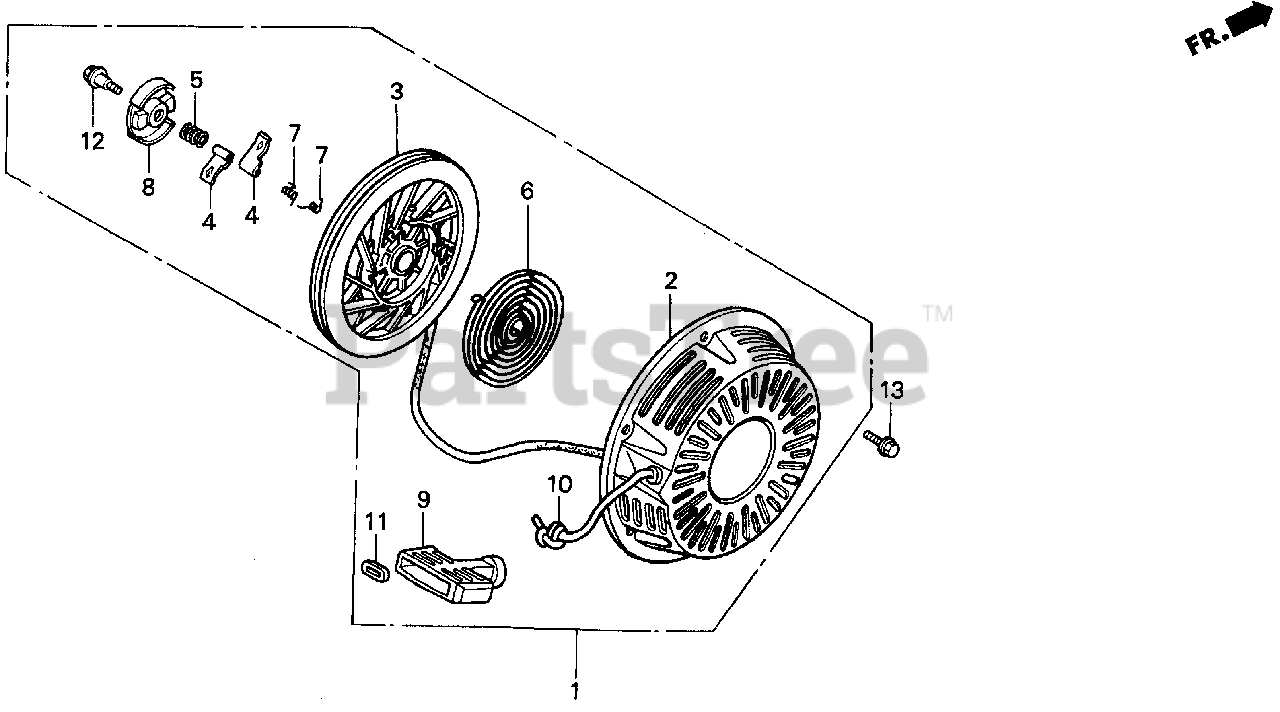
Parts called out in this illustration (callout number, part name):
1	STARTER ASSY., RECOIL *R8* (BRIGHT RED)
2	CASE, RECOIL STARTER *R8* (BRIGHT RED)
3	PULLEY, RECOIL STARTER
4	RATCHET, STARTER
5	SPRING, FRICTION
6	SPRING, STARTER RETURN
7	SPRING, RATCHET
8	RETAINER, SPRING
9	GRIP, STARTER
10	ROPE, RECOIL STARTER (N/A: USE P/N 08560-ZG921-11)
11	GRIP, REINFORCEMENT
12	SCREW, CENTER
13	BOLT, FLANGE (6X10)
